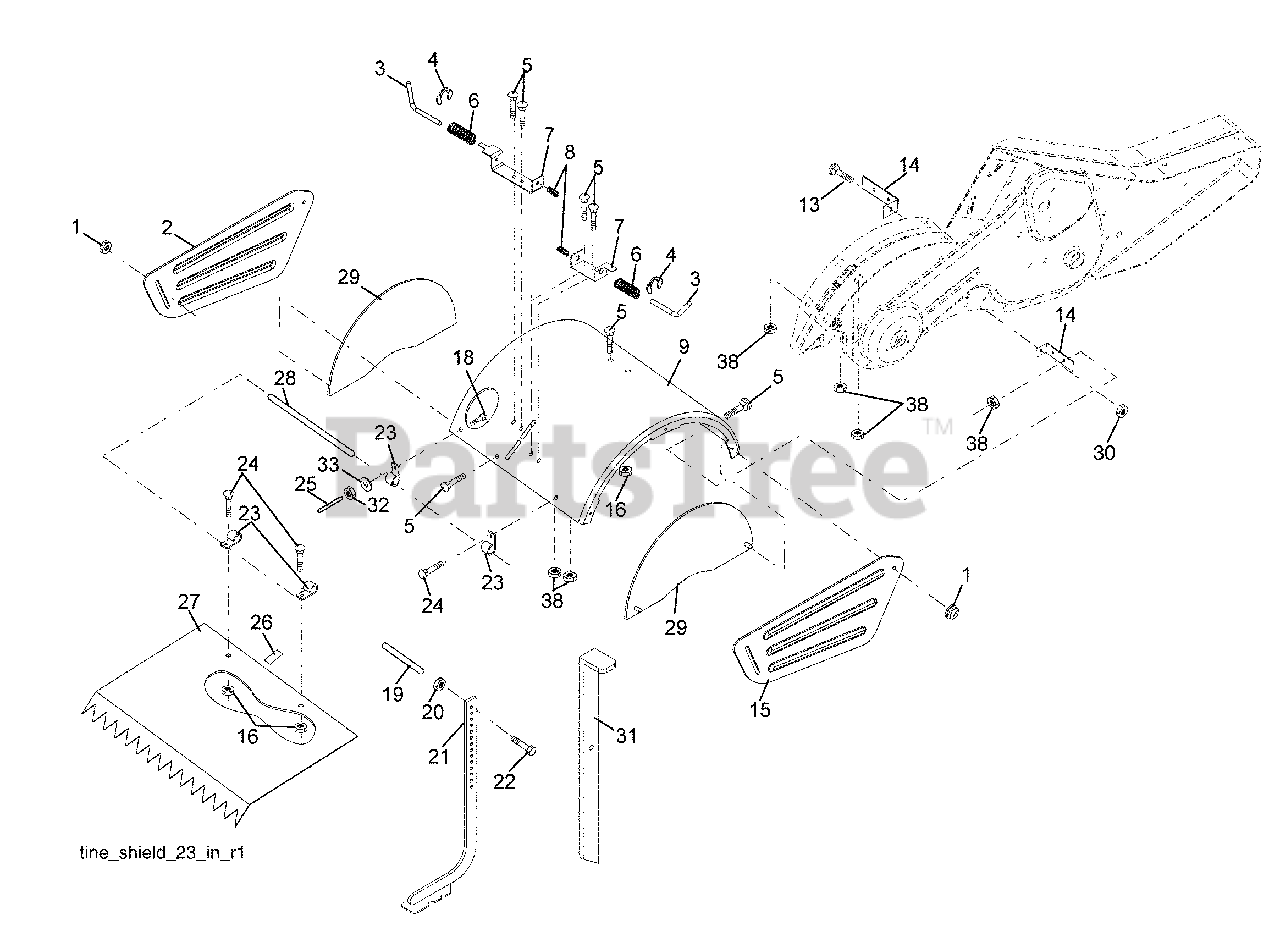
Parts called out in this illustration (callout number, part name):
1	Nut, Lock Hex Flange 5/16-18 unc
2	Shield, Side, Outer L. H.
3	Pin, Stake, Depth
4	Ring, Klip
5	Bolt Rdhd Sqnk 5/16-18 x 3/4
7	Bracket, Latch
8	Spring, Depth Stake
9	Shield, Tine
10	Bolt, Carriage 5/16-18 x 1-1/4
11	Bracket, Shield Tine
12	Shield, Side, Outer R.H.
13	Nut, Hex Flange 1/4-20
14	Bolt, Carriage 1/4-20 x 1-1/4 Gr. 5
16	Nut, Hex 3/8-16
17	Stake, Depth
18	Bolt, Hex 3/8-16 x 2
20	Bolt, Carriage 1/4-20 x 1/2
21	Cap, Vinyl
22	Pad, Idler
23	Shield, Leveling
24	Pin, Hinge
25	Nut Lock Flange
26	Shield, Side
27	Stake, Drag
28	Nut, Fin, Hex 1/4-20 unc
29	Washer Lock Hvy Helical 1/4
30	Nut Keps Hex 5/16-18 unc
